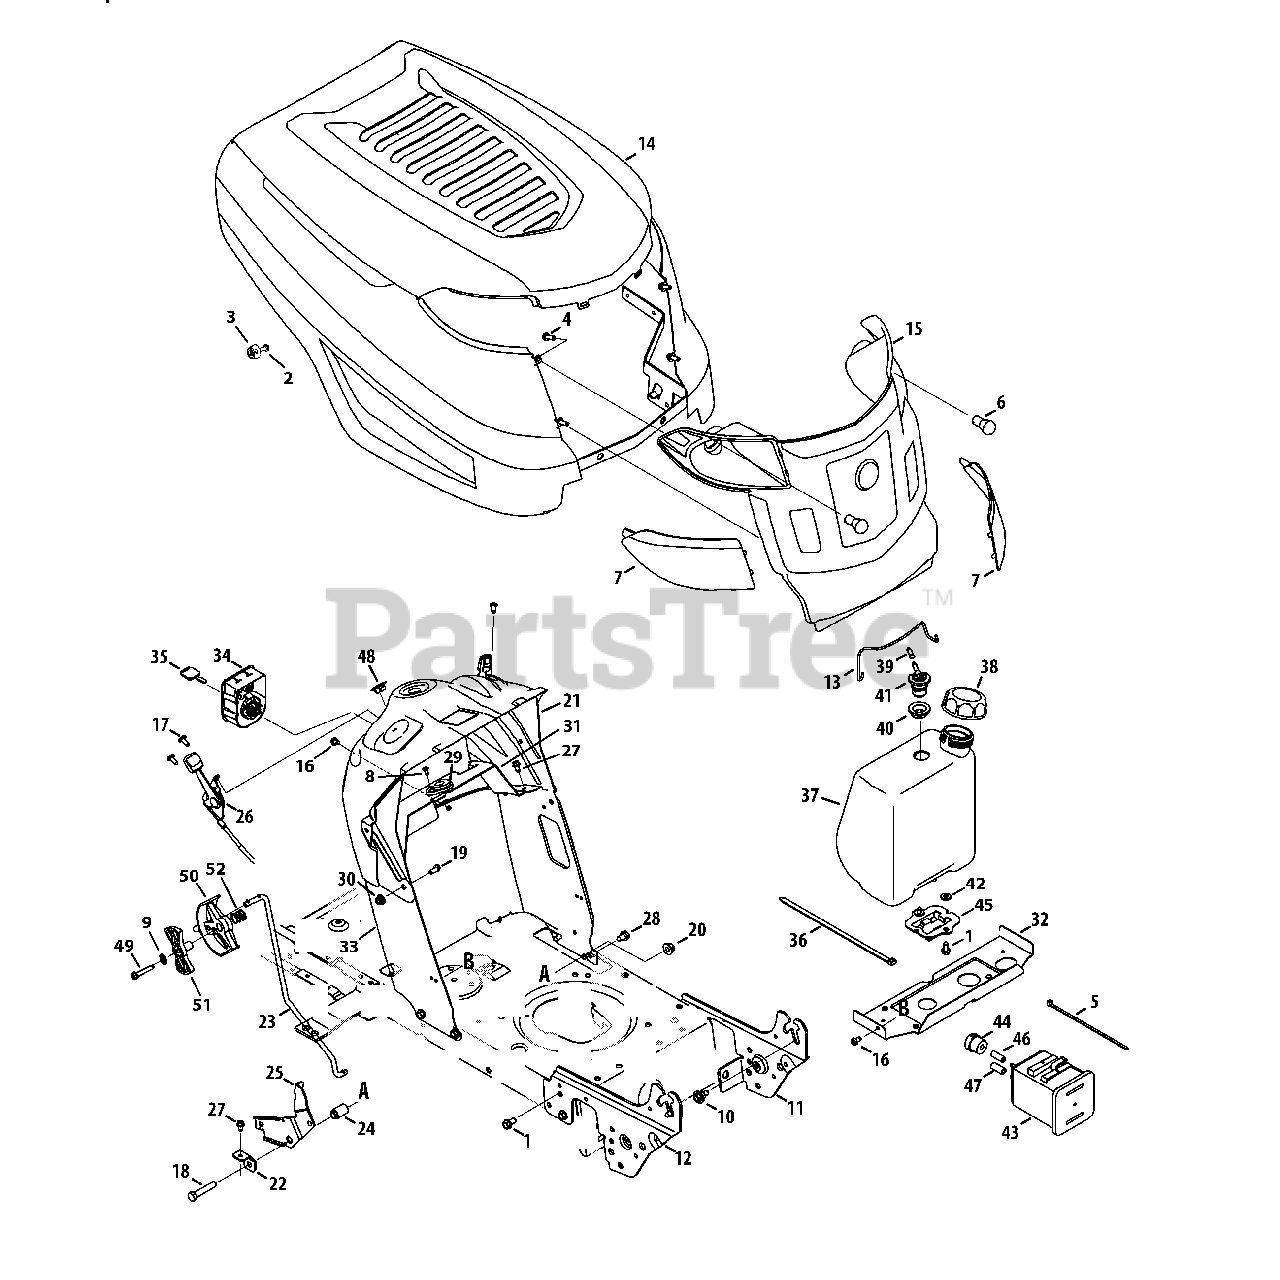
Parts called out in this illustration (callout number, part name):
1	Screw 5/16-18 x .750
2	Screw, #12-16 x 1.25
3	K-Style Bumper
4	Screw, 1/4 x .750
5	Cable Tie
6	Miniature lamp 12V socket
7	Grill Lens - LH
7	Grill Lens - RH
8	Screw, #10-16 x .500
9	Lock Washer, 1/4
10	Shoulder Screw .43 x .29
11	Suppport Bracket LH
12	Suppport Bracket RH
16	Screw, 1/4-20 x .500
17	Screw 1/4-20 x .500
18	Hex Screw 3/8-16 x 2.00
19	Hex Screw, 5/16-18 x .625
20	Flange Lock Nut 3/8-16
21	Dash, Upper
22	Speed Latch Tab
23	Speed Control Rod
24	Flange Spacer .39 x .671 x 1.095
25	Transmission Speed Latch
26	Throttle/Choke Control Cable
27	Tap Screw, 1/4-20, 0.625
28	Screw 5/16-18 x .625
29	Bearing, .628 ID x 1.36
30	Flange lock Nut 5/16-18
31	Bracket, Steering Support
32	Gas Tank Support Bracket
33	Dash, Lower
34	Key Switch Module
35	Key, Assembly
36	Cable Tie
37	Fuel Tank, 1.36 Gallon
38	Fuel Cap Grey
38	Fuel Cap, CARB Black
39	Hose Vent, 3/16
40	Rubber Grommet
41	Rollover Valve
42	Washer, Flat, .344 x .750 x .120
43	Canister, Carbon, 5 Gallon
44	Filter, Vent, Canister
45	Bracket., Adapter, Canister
46	Hose, Fuel, Low Perm., White
47	Hose, Fuel, Low Perm., Yellow
48	Choke Plug
49	Hex Washer Screw, 1/4-20 x 1.50
50	Shift Lever
51	Index Control
52	Compr. Spring, .72 OD x .78
